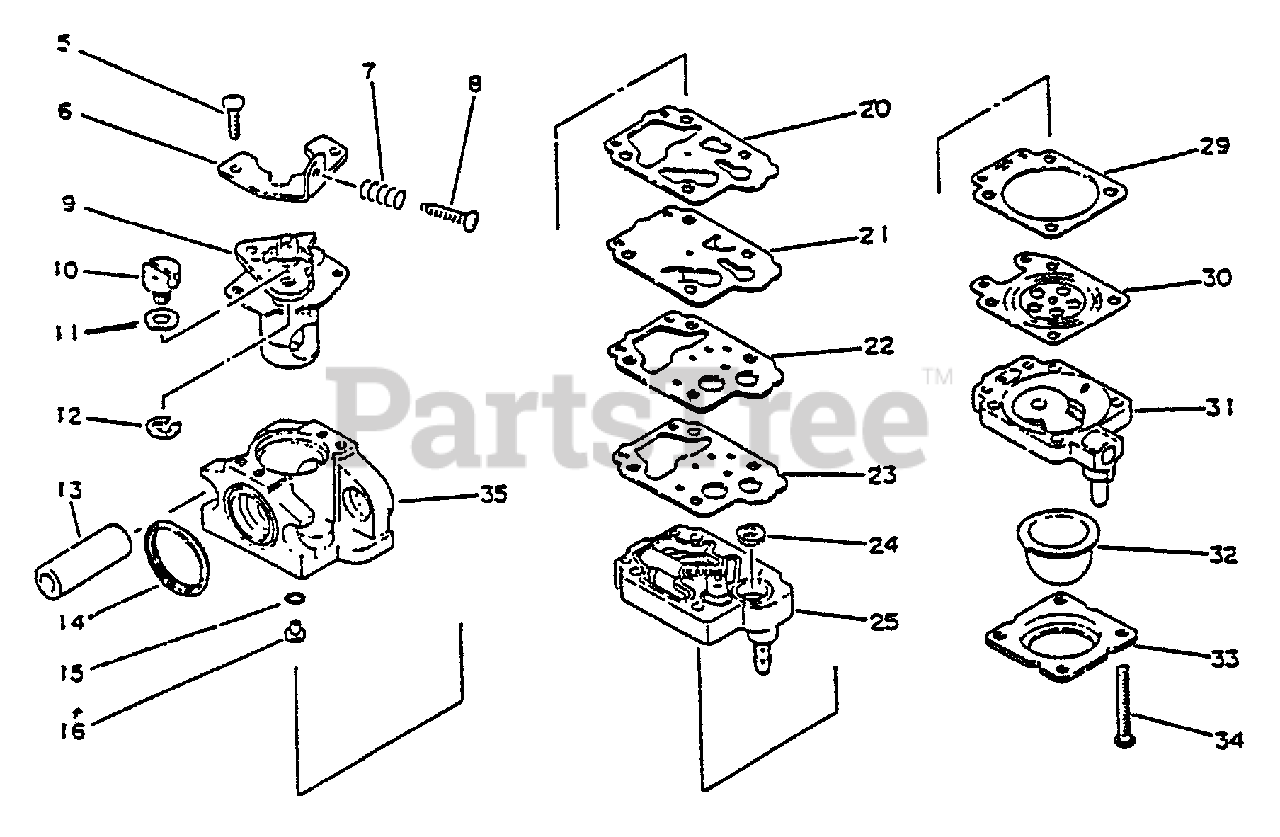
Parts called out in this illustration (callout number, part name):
6	BRACKET, THROTTLE CABLE
7	SPRING, IDLE ADJUST
8	SCREW, IDLE ADJUST
9	VALVE, THROTTLE
12	RING, RETAINING
13	SLEEVE, MOUNTING
14	SEAL
15	O-RING
16	JET
20	GASKET, PURGE
21	DIAPHRAGM, PURGE
22	PLATE, PUMP
23	GASKET, PLATE
24	STRAINER
25	BASE, PURGE
29	GASKET, METERING
30	DIAPHRAGM, METERING
31	BASE, PURGE
32	BULB, PURGE
33	RETAINER, PURGE BULB
35	BODY, CARBURETOR
